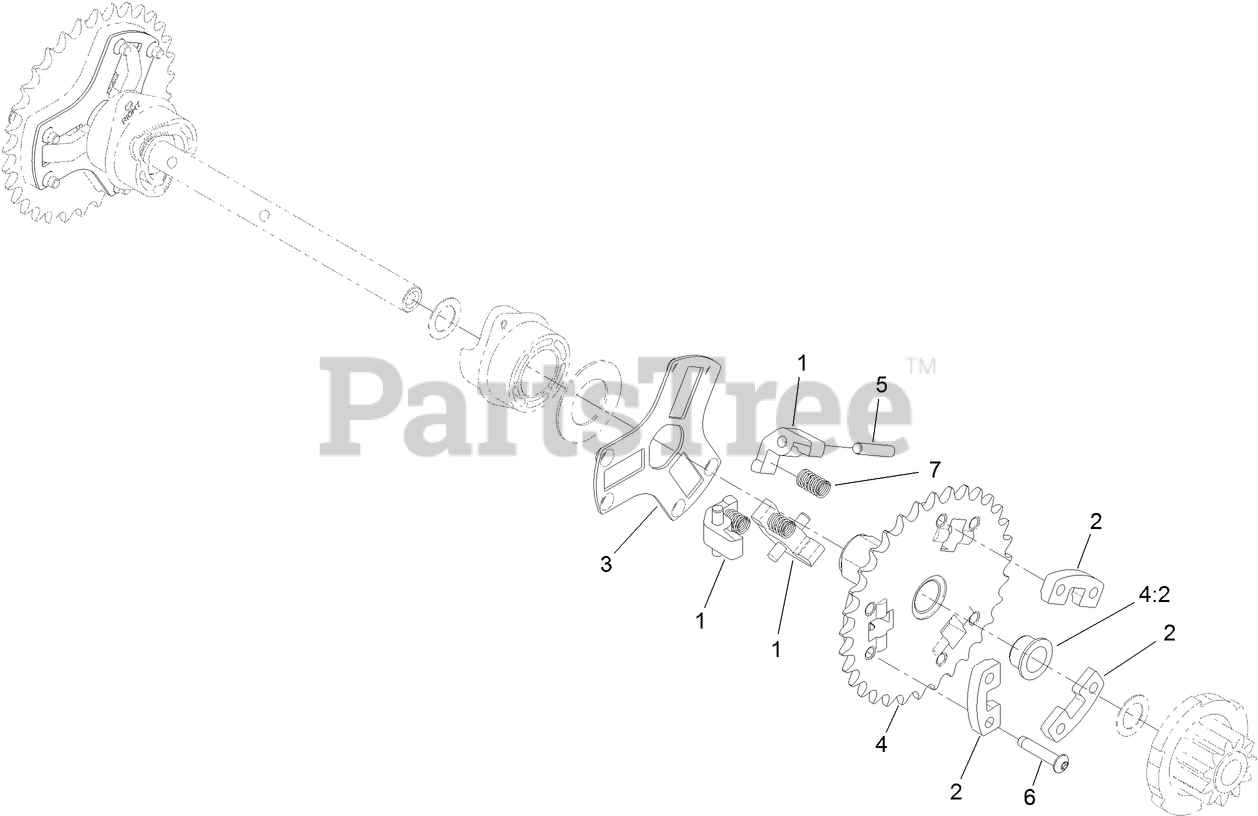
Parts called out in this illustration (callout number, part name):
1	PAWL-CLUTCH
2	SUPPORT-PAWL
3	RETAINER-PAWL, PIN
4	32T SPROCKET ASM
4:2	BUSHING-FLANGE
5	PIN-DOWEL
6	SCREW-BHCS
7	SPRING-COMPRESSION
